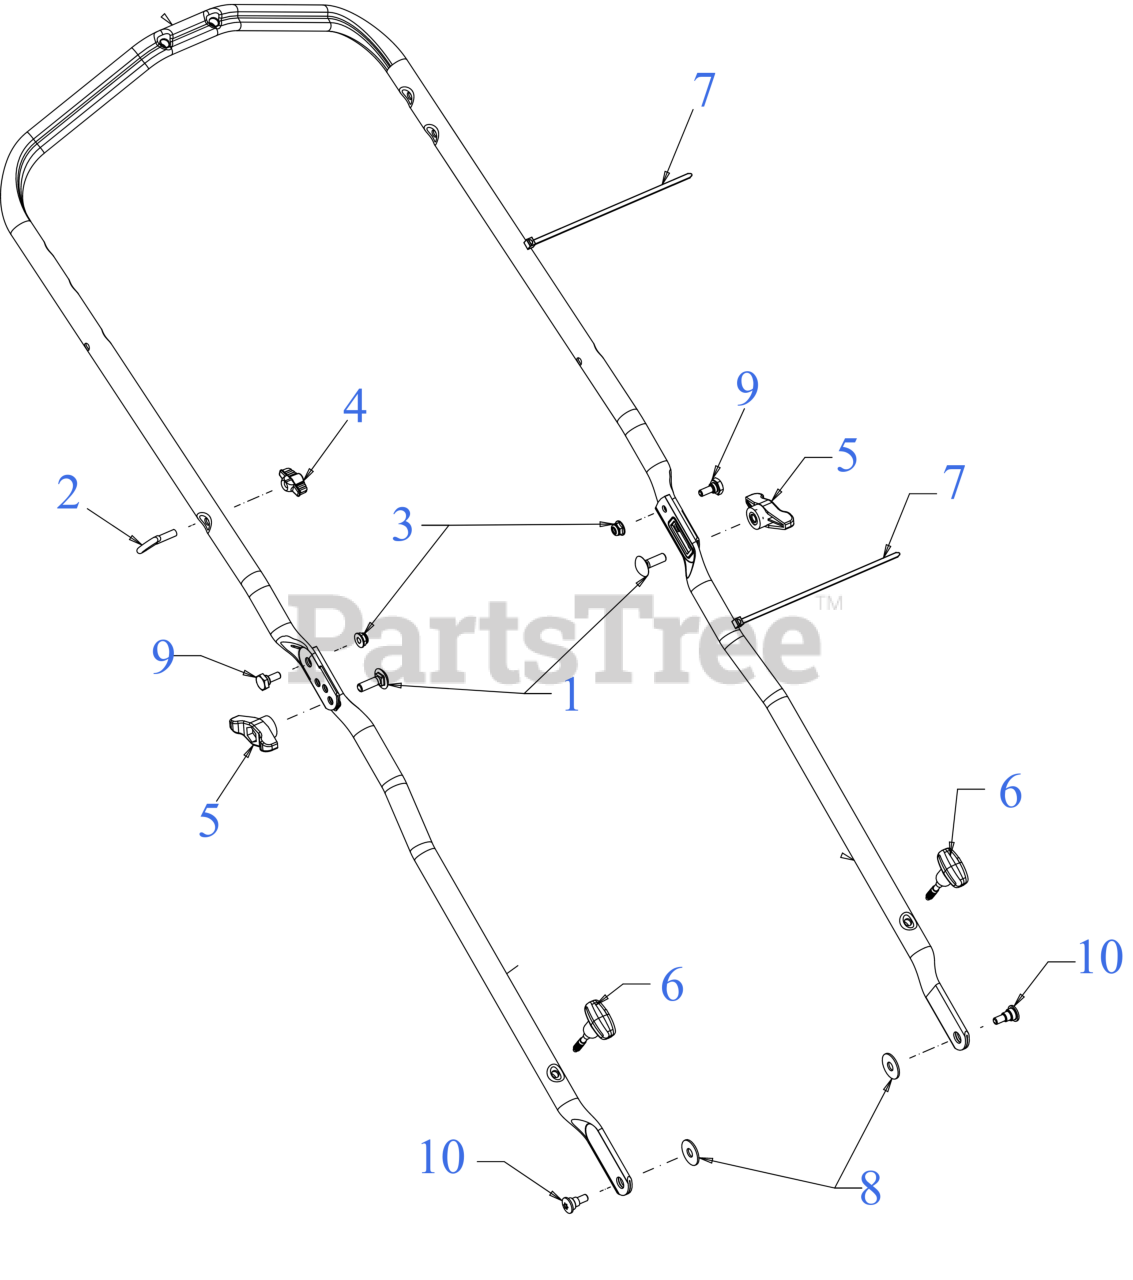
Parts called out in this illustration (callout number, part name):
1	SCREW 5/16-18 x 1.00 GR5
2	EYEBOLT 1/4-20
3	FLANGE LOCK NUT
4	HANDLE KNOB
5	WING KNOB 5/16-18
6	WING KNOB 1/4-20 x 1.80
7	7" CABLE TIE
8	FLAT WASHER 344X1.00
9	SHOULDER SCREW
10	SHOULDER SCREW .450X .188X 1/4-20
